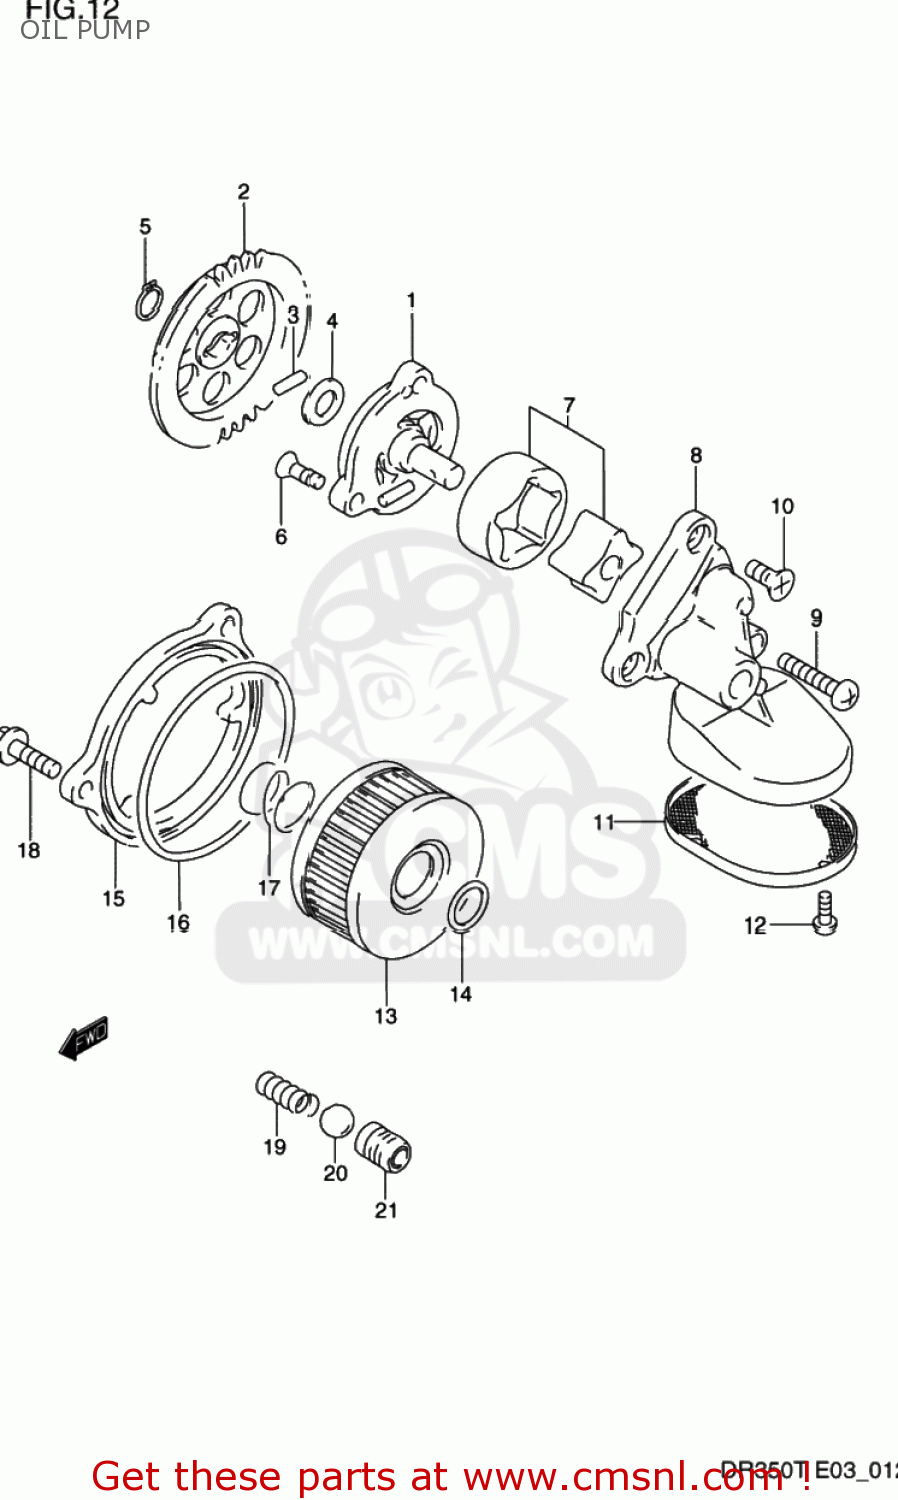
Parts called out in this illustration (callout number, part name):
1	PUMP ASSY,ENGINE OIL NO.1
2	GEAR,OIL PUMP DRIVEN
3	PIN(4X15.8)
4	SHIM
5	CIRCLIP,10MM
6	SCREW ,6X16
7	ROTOR SET,OIL PUMP,NO.2
8	COVER,OIL PUMP NO.2
9	SCREW,6X30
10	SCREW ,6X16
11	STRAINER,OIL PUMP NO.2
12	SCREW
13	FILTER ASSY,ENGINE OIL
14	O RING(D:2.4,ID:15.8)
15	CAP,OIL FILTER
16	O RING(D:2.4,ID:73)
17	SPRING
18	BOLT
19	SPRING
20	BALL
21	SEAT,OIL CHECK VALVE
